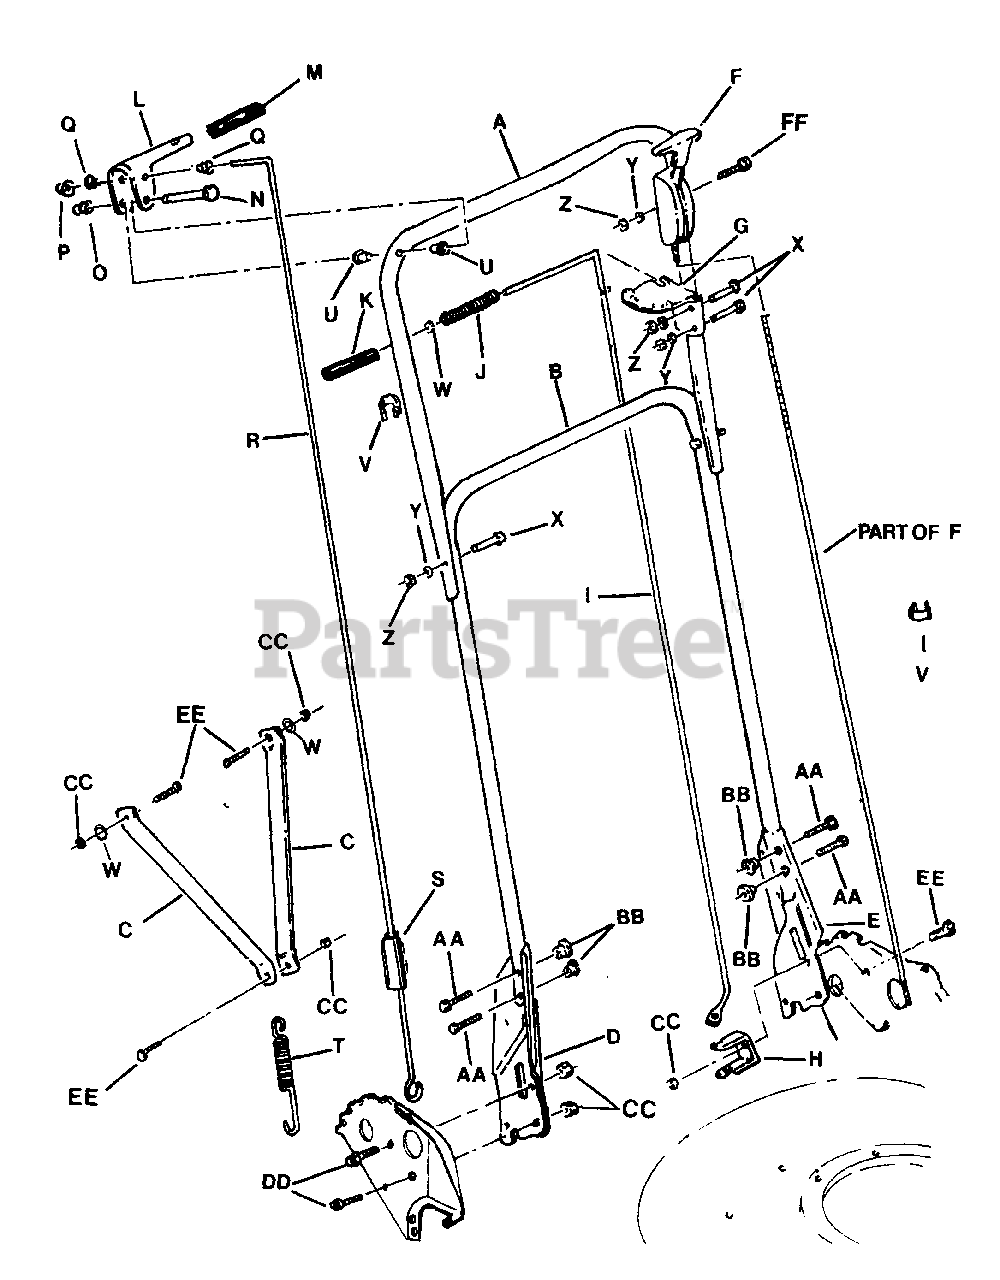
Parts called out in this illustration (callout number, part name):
A	HANDLE, UPPER
B	HANDLE, MIDDLE
C	STRAP, HANDLE
D	MOUNT, RIGHT HAND HANDLE
E	MOUNT, LEFT HAND HANDLE
F	CONTROL, Throttle, 49.0" - B&S
F	CONTROL, THROTTLE, 44.375" - Robin
F	CONTROL, THROTTLE, 49.0" - Honda
G	SECTOR, SPEED CONTROL
H	ANCHOR, Speed Control
I	LEVER, SPEED CONTROL
J	SPRING, SPEED CONTROL LEVER
K	GRIP, SPEED CONTROL LEVER
L	HANDLE, Clutch
M	GRIP, CLUTCH HANDLE
N	PIN, CLUTCH HANDLE
O	NUT, PUSH
P	NUT, PUSH
Q	BUSHING, PULL ROD
R	ROD, CLUTCH PULL
S	COVER, VINYL
T	SPRING, CLUTCH
U	BUSHING, CLUTCH HANDLE PIN
V	CLIP
W	WASHER, FLAT 5/16
X	SCREW, CAP 1/4-28 X 1 3/8
Y	WASHER, INTERNAL TOOTH LOCK 1/4
Z	NUT, HEX 1/4-28
AA	SCREW, CAP 1/4-20 X 1
BB	NUT, CURVED HEAD T 1/4-20
CC	NUT, LOCK 5/16 - 24
DD	CAPSCREW, 5/16-24 x 1
EE	CAPSCREW, 5/16-24 x 3/4
FF	CAPSCREW, 1/4-28 x 1 3/4
